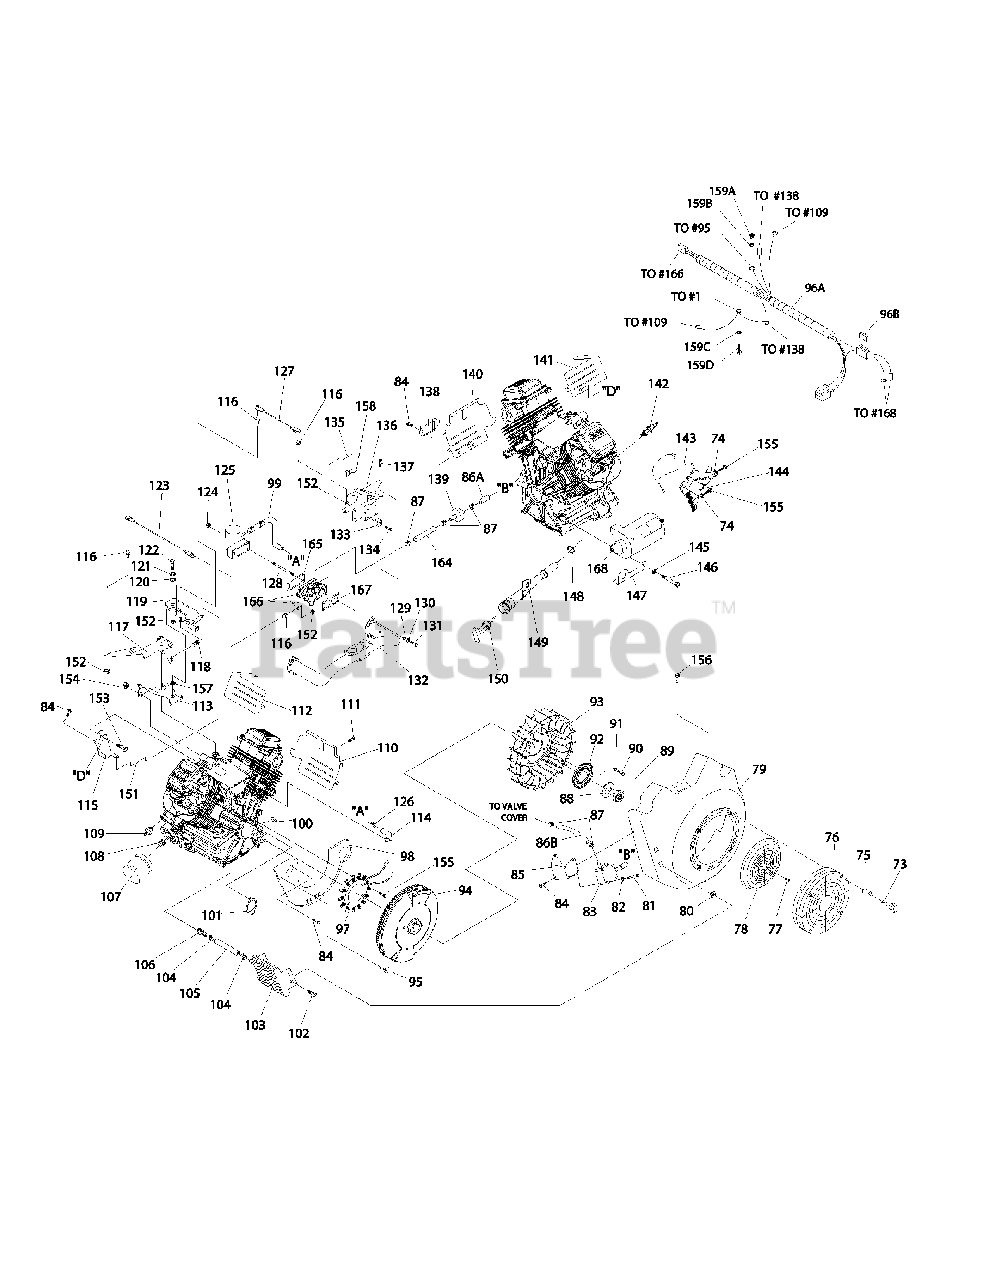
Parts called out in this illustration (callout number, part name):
73	KNOB AIR CLEANER
74	WASHER, LOCK M6-1/4"
75	SPACER, ROTATING SCREEN GUARD
76	GUARD, ROTATING SCREEN
77	SCREW, #10 SHEET METAL
78	SCREEN, ROTATING
79	HOUSING, BLOWER VERTICAL
80	NUT, GROMMET 1/4 PLUG
81	SCREW PPHM M4-0.7 X 40
82	WASHER, LOCK M4
83	PUMP, IMPULSE
84	SCREW TAPTITE M6-1.0X 10 YELLOW CHROME
85	BRACKET, FUEL PUMP
86A	HOSE ¼" ID X 2" LONG
86B	HOSE ¼" ID X 7" LONG
87	CLAMP HOSE BAND 1/4
88	WASHER, M24
89	NUT,HEX M24
90	SCREW HHC M8-1.25 X 10 G8.8
91	WASHER SHAKEPROOF INT M8 SS
92	PLATE, FAN
93	FAN, NYLON
94	FLYWHEEL ASSEMBLY
95	INSULATOR ASSEMBLY IGNITION
96A	VS WIRE HARNESS
96B	30 AMP FUSE
97	ASSEMBLY, STATOR W/ LUGS
98	PLATE, BACKING WITH OIL COOL
99	ASSY,BREATHER TUBE
100	KEY, WOODRUFF 4 X 19D
101	GASKET, MANIFOLD / PORT
102	PLASTITE,1/4-15 X 3/4
103	COOLER, OIL
104	CLAMP HOSE .38 - .87
105	HOSE, 3/8" I.D. X 6" LONG
106	BARBED STR 1/4NPT X 3/8 WITH VIBRA SEAL
107	FILTER, OIL D 69 X 64 LONG
108	NIPPLE, 3/4"-16 UNF
109	SWITCH, OIL PRESS
110	WRAPPER, LOWER CYLINDER 1
111	SCREW THTT #10-24 X 3/8"
112	WRAPPER, UPPER CYLINDER 1
113	BRACKET, SUPPORT-GOVERNOR ADJUST
114	HOSE, BLOWER HSG TO BREATHER
115	ASSY, IDLE SPEED SUPPORT BRACKET
116	STUD, BALL M3-0.5
117	ASSY, GOVERNOR LEVER
118	SPRING, GOVERNOR
119	ASSY, IDLE SPEED ADJUST W/ GROMMET
120	WASHER, FLAT M5
121	WASHER, LOCK M5
122	SCREW, HHC M5-0.8 X 10
123	ROD, GOVERNOR
124	NUT LOCK FLANGE M6-1.0
125	ADAPTOR,CARB-AIRBOX,M6 BOSSES
126	HOSE CLAMP, BAND 12mm I.D.
127	ASSEMBLY, IDLE SPEED ADJUSTMENT ROD
128	STUD, METRIC
129	WASHER, FLAT M8
130	WASHER, LOCK M8
131	SCREW, SHC M8-1.25 X 30
132	MANIFOLD,INTAKE 2BBL CARB
133	CLAMP, 3/16" COATED CABLE
134	SCREW, PPHM M5-0.8 X 12
135	ROD, CHOKE
136	ASSY, BELDEN BRACKET W/ BELLCRANK
137	SCREW HHFC M6-1.0 X 8mm
138	REGULATOR, 20 AMP
139	FILTER, FUEL
140	WRAPPER, LOWER CYLINDER 2
141	WRAPPER, UPPER CYLINDER 2
142	SPARK PLUG RC12YC
143	ASSEMBLY, GROUND WIRE
144	ASSEMBLY, IGNITION COIL
145	WASHER, LOCK M8-5/16
146	SCREW, HHC M8-1.25 X 85 G8.8
147	LIFT HOOK, STARTER
148	O-RING, OIL CLR
149	TUBE, DIPSTICK
150	ASSEMBLY, DIPSTICK W/ HANDLE
151	ROD, IDLE ADJUSTMENT
152	NUT, LOCK HEX M3-0.5
153	SCREW, SHC M10-1.5 X 75 G10.9
154	NUT, LOCK FL-SERRATED M10-1.5
155	SCREW, TAPTITE M6-1.0 X 25
156	SCREW, FHHC M6-1.0 X 12 W/M5 HEX
157	WASHER NYLON 0.375" I.D.
158	BUSHING, GOVERNOR ROD
159A	NUT HEX #8-32
159B	WASHER LOCK #8-M4
159C	WASHER LOCK M3
159D	SCREW PPHM M3-0.5 X 8
164	HOSE ¼" ID X 8.5" LONG
165	GASKET, CARB TO SPACER
167	GASKET, MANIFOLD TO CARB
168	STARTER, V-TWIN ENGINE
